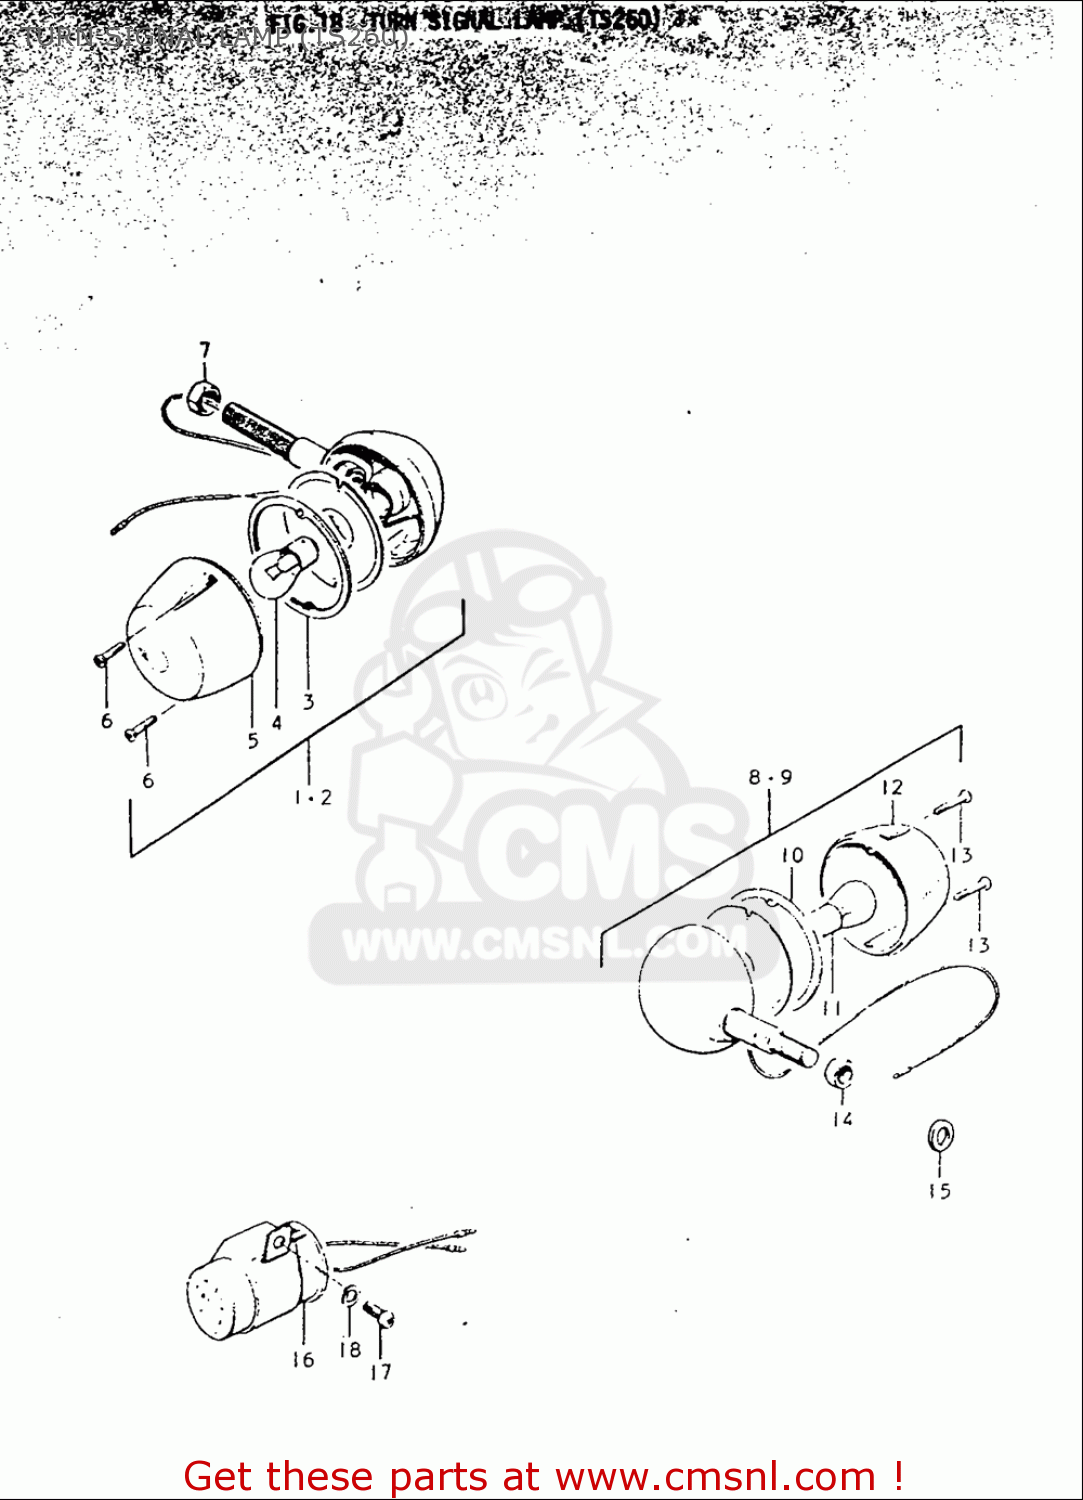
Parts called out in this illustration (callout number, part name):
3	GASKET,TURNSIGNAL LENS (NAS)
4	BULB(6V17W,STANLEY,A4513A)
5	LENS,TURNSIGNAL
6	SCREW
7	NUT
10	GASKET,TURNSIGNAL LENS (NAS)
11	BULB(6V17W,STANLEY,A4513A)
12	LENS,RR TURNSIGNAL LAMP
13	SCREW
14	NUT
15	WASHER
17	SCREW
18	WASHER,LOCK
